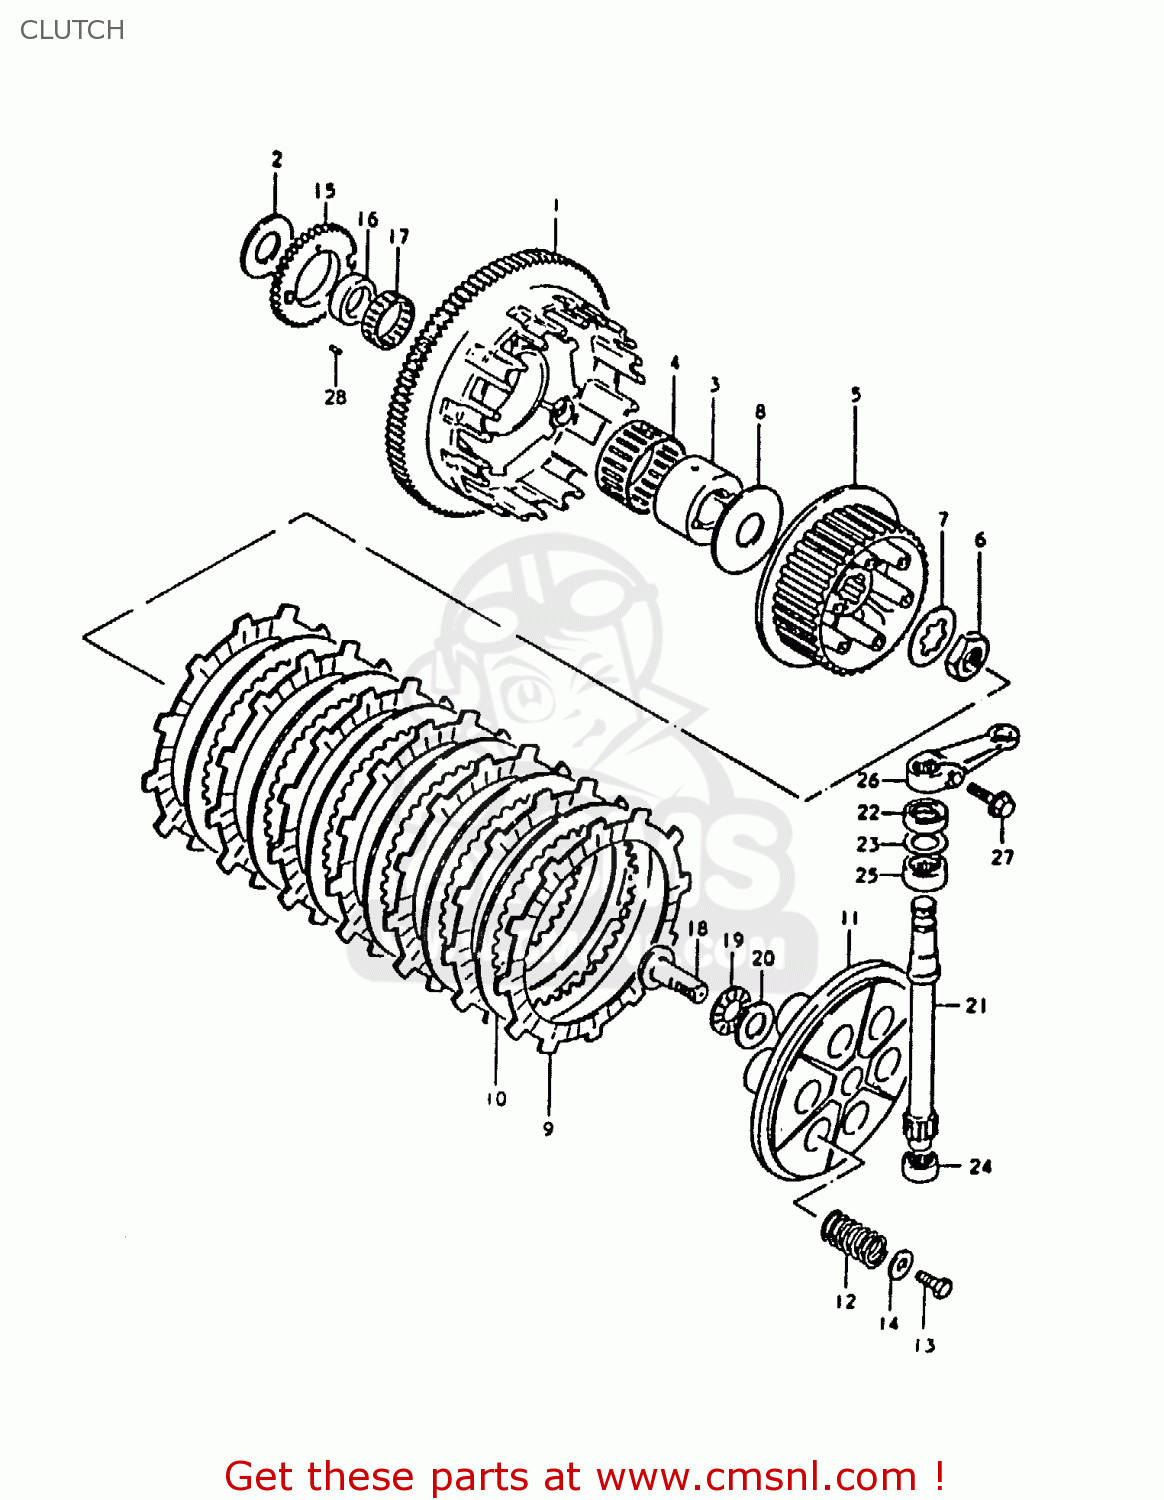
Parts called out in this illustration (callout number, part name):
1	GEAR ASSEMBLY,PRIMARY DRIVE
2	WASHER
3	SPACER,PRIMARY DRIVEN
4	BEARING
5	HUB,CLUTCH SLEEVE
6	NUT
7	WASHER,LOCK
8	WASHER(25X66X3.5)
9	PLATE,CLUTCH DRIVE (MCA)
10	PLATE,CLUTCH DRIVEN (NAS)
11	DISC,CLUTCH PRESSURE
12	SPRING
13	BOLT, UPPER
14	WASHER
15	GEAR,OIL PUMP DRIVE
16	SPACER,OIL PUMP DRIVE GEAR
17	BEARING(36X40X10)
18	RACK,CLUTCH RELEASE
19	BEARING(15X28X2)
20	WASHER
21	PINION,CLUTCH RELEASE
22	OIL SEAL
23	WASHER (14.2X22X1)
24	BEARING(12X19X12)
25	BEARING(15X22X12)
26	ARM,CLUTCH RELEASE
27	BOLT
28	CUSHION,PRIMARY DRIVEN GEAR
